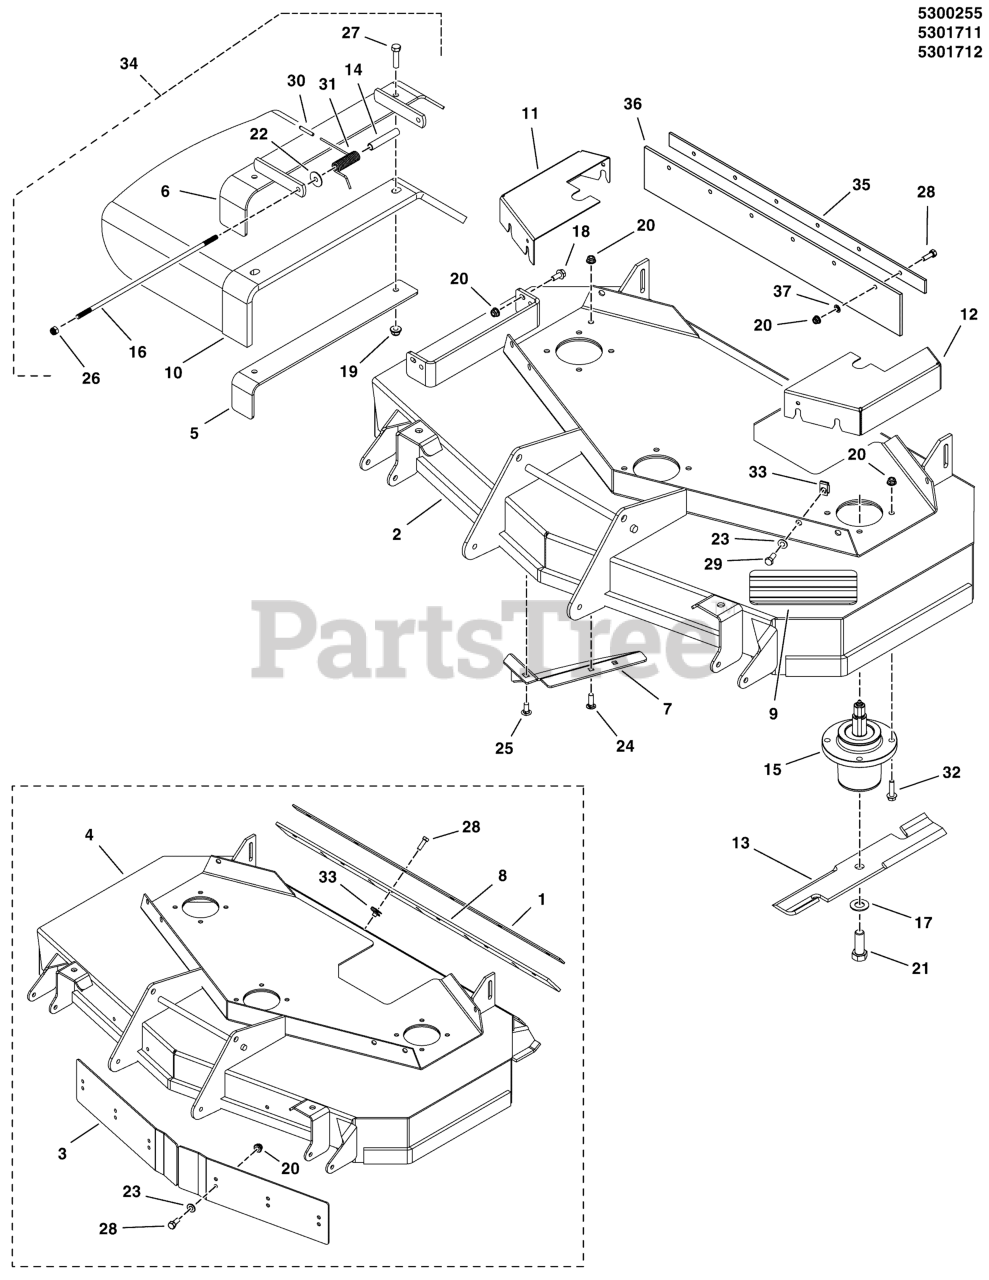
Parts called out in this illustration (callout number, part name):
1	BAR, RETAINING, 44RD - BLK
3	BAFFLE, FRONT DISCHARGE, 44RD - BLK
4	DECK SHELL W/DECALS, 44RD, IS1500ZCE
5	SUPPORT, DISCHARGE CHUTE, 48/52 - BLK
6	WELD, MOUNT, DISCHARGE CHUTE - BLK
7	WELD, DISCHARGE BAFFLE, 44" - BLK
8	FLAP, RUBBER, 44RD
9	SAFETY WALK, 4.00 X 7.50
10	CHUTE, DISCHARGE, BEND RUBBER, 44/48/52
11	GUARD, 44" MOWER DECK, RH
12	GUARD, 44" MOWER DECK, LH
13	BLADE, 15" (SET OF THREE)
14	SPACER, TORSION SPRING,9.63 LG
15	ASSM, SPINDLE, LOW PROFILE
16	ROD, 5/16 X 13.75, TBE, CZ
17	WASHER, 5/8 GRADE 8, YZ
18	BOLT, 5/16-18 X 3/4 GD5
19	NUT, 3/8-16 HEX NYLOCK FLANGE
20	NUT, 5/16-18 HEX NYLOCK FLANGE
21	BOLT, 5/8-11 X 1-3/4 GD8
22	WASHER, 5/16 FENDER
23	WASHER, 5/16" SAE
24	BOLT, 5/16-18 X 1, CARRIAGE
25	BOLT, 5/16-18 X 3/4, CARRIAGE
26	NUT, 5/16-24 HEX NYLON LOCK
27	BOLT, 3/8-16 X 1-1/2" GD5 CZ
28	BOLT, 5/16-18 X 1 GD5 YZ
29	BOLT, 5/16-18 X 3/4 GD5
30	CAP, PROTECTOR, .120 ID
31	SPRING, TORSION
32	BOLT, 5/16-18 X 1 1/4 FLANGE
33	BODY CLIP, 5/16-18-7GA MATERIAL
34	KIT, DISCHARGE CHUTE, 44/48/52
35	PLATE, SUPPORT, 48 - BLK
36	FLAP, RUBBER, 48
37	5/16 PUSH-ON NUT RETAINER, STL, CZ
